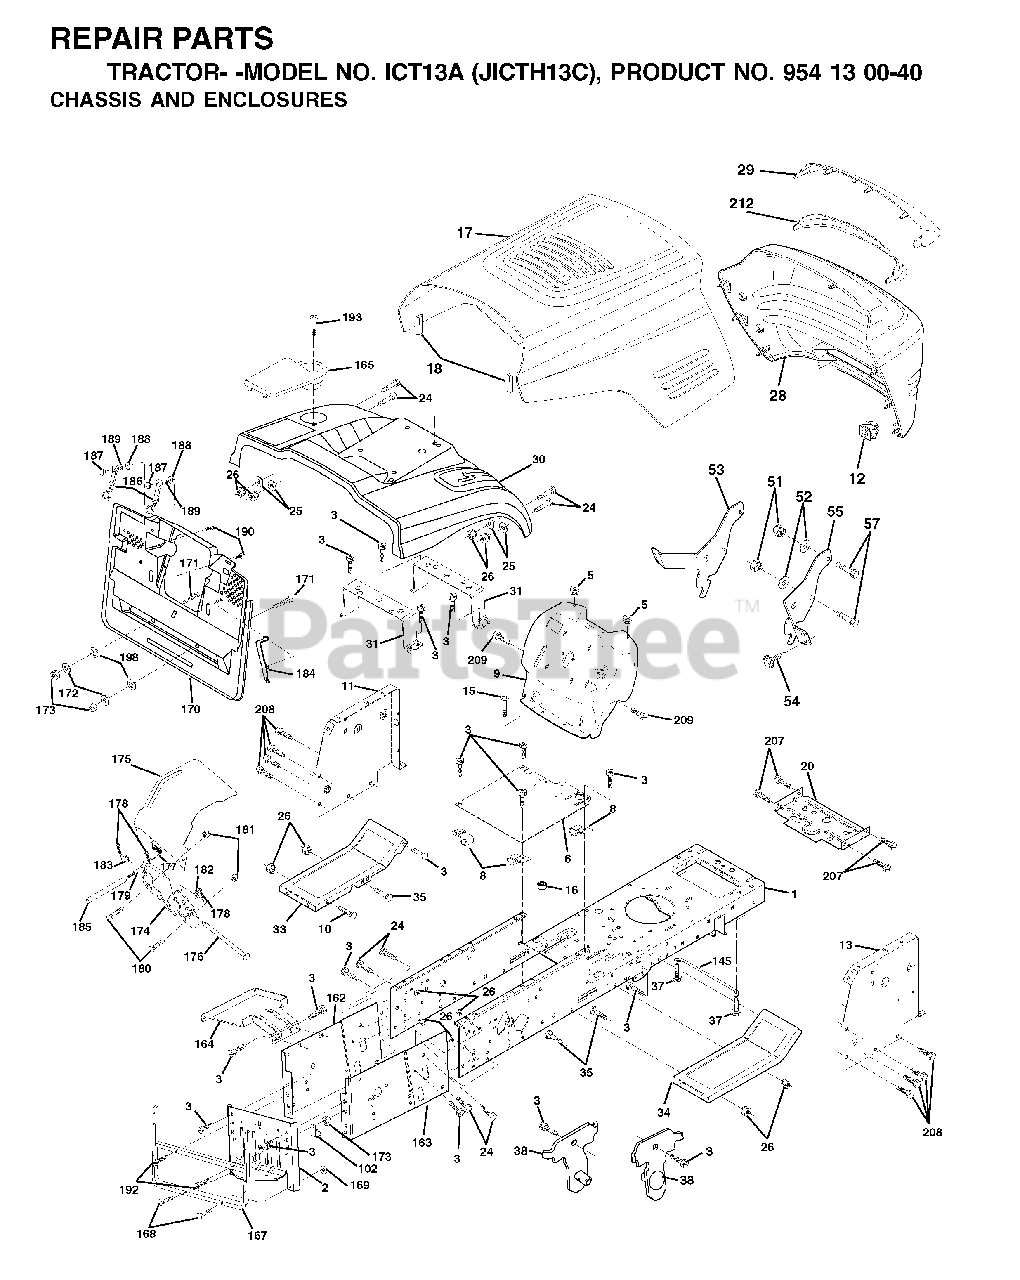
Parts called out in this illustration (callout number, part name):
1	CHASSIS STAMPING
3	SCREW 3/8-16X3/4
5	BUMPER.RUBBER.HOOD
6	SADDLE FLAT
8	CLIP,INSULATOR
10	BOLT D
11	PANEL DASH LH
13	DASH PANEL RH
16	NUT
18	BUMPER HOOD T
20	PLATE MTG
25	WASHER
26	NUT
31	BRACKET SUPPORT FENDER
38	BRACKET
51	LOCKNUT
57	BOLT
102	CLIP T
145	ROD PIVOT CHASSIS/HOOD
164	SUPPORT
168	BOLT.ROUND.HEAD.SQUARE.NECK
169	NUT T
170	BACKPLATE ASM
172	WASHER
176	HINGE PIN
177	SPRING COVER LH
178	COTTER PIN
179	ROD PIVOT
180	BOLT RB
181	LOCKNUT
185	TUBE LEVER
186	LATCH ASSY
187	WELDNUT
189	LOCKWASHER
192	SCREW LT
193	SCREW, TRUSS 1/4-20 X 3/4"
207	SCREW, 5/16-18 X 1/2
208	SCREW 3/8-16X1/2
209	SCREW, 3/8-16X3/4
